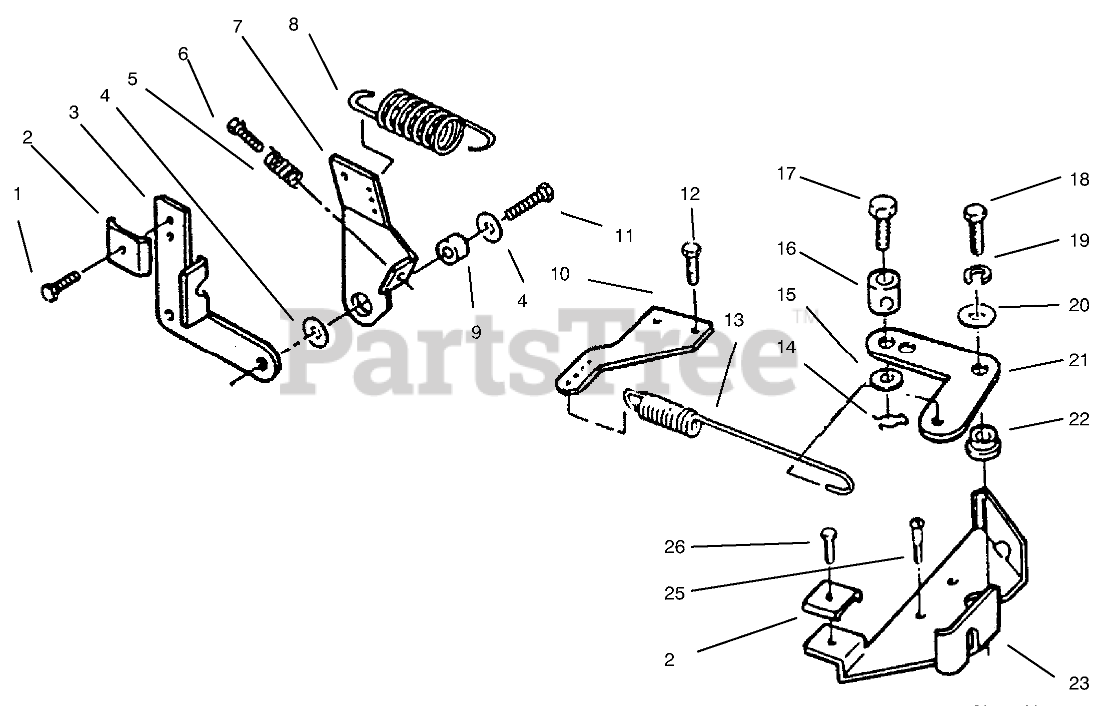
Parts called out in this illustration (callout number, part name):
1	SCREW-TAPPING
3	BRACKET-GOVERNOR
4	WASHER-FLAT
5	SPRING
6	SCREW-TAP
7	GOVERNOR CONTROL ARM
8	SPRING
9	BUSHING
10	ADAPTER-GOV ARM
11	SCREW-HWH
12	SCREW-TAPPING PAN HD
13	SPRING-GOV
14	PIN-COTTER
15	WASHER-FLAT
16	BUSHING
17	SCREW
18	SCREW - CAP HEX HEAD
19	WASHER-LOCK, SPRING
20	WASHER-FLAT
21	Governor Control Arm
22	BUSHING-GOV CONTROL
23	BRKT-GOVERNOR CONTRL
25	HEX HD CAP SCREW
26	TAPPING HEX HD CS
